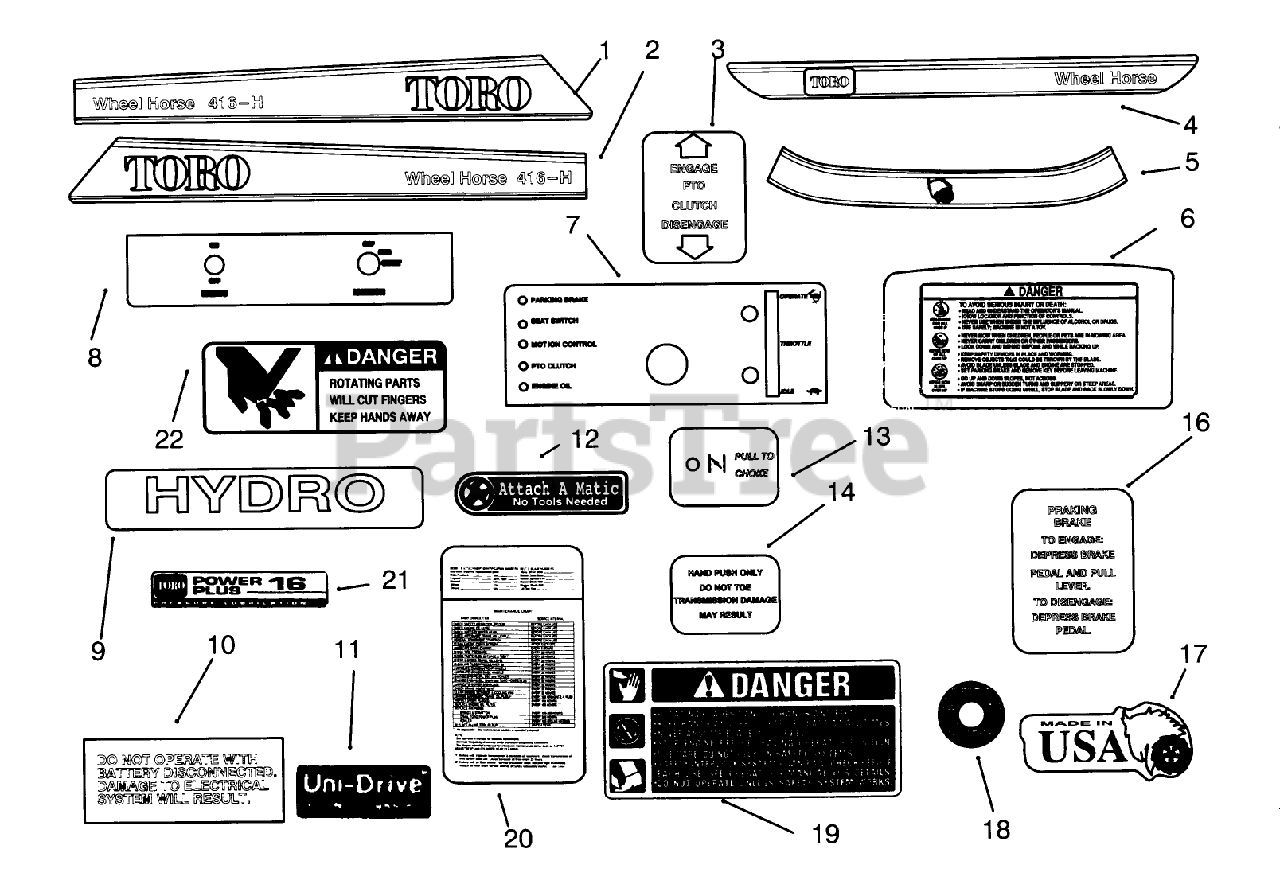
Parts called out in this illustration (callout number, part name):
3	DECAL PTO CLUTCH
4	DECAL-FENDER
8	DECAL-BACK PLATE
13	DECAL-CHOKE
14	DECAL-DO NOT TOW
16	DECAL-PARKING BRAKE
18	KOHLER 41-113-02
19	DECAL-DANGER
21	DECAL-PWR PLUS 16 PL
22	DECAL - DANGER
